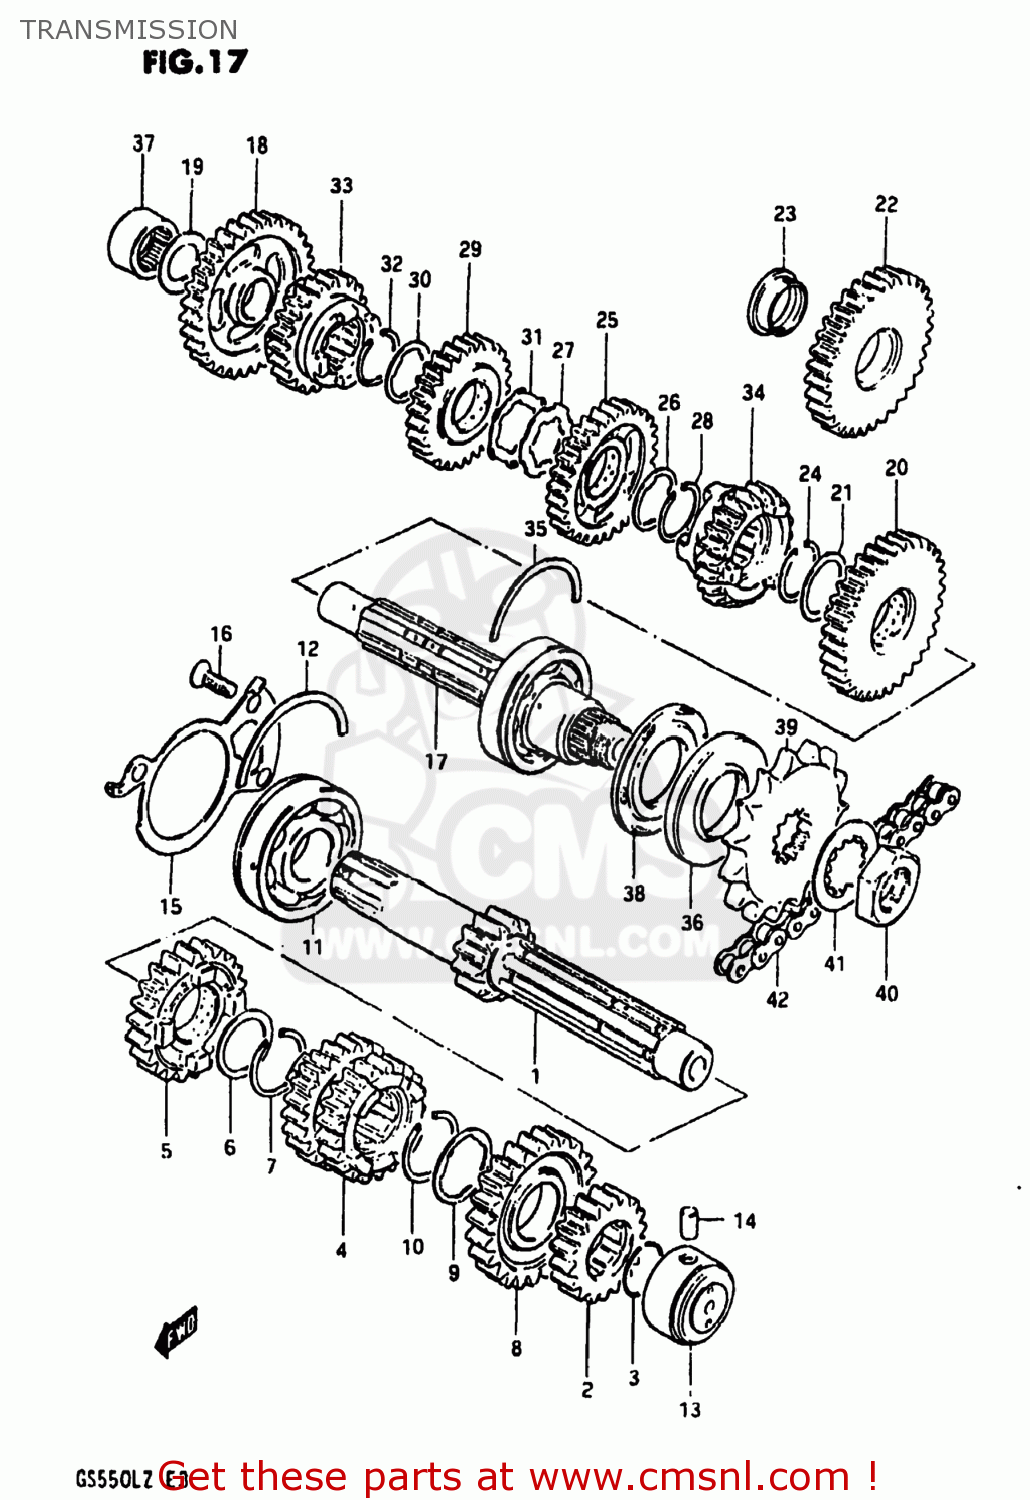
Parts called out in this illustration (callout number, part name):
1	SHAFT,COUNTER
2	GEAR,SECOND DRIVE
3	RING,SNAP
4	GEAR,THIRD DRIVE
5	GEAR,FIFTH DRIVE
6	WASHER
7	CIRCLIP
8	GEAR,SIXTH DRIVE
9	WASHER,LOCK
10	CIRCLIP
11	BEARING(25X62X17)
12	C-RING
13	BEARING
14	PIN
15	PLATE,COUNTERSHAFT BEARING
16	SCREW
17	SHAFT,DRIVE
18	GEAR,FIRST DRIVEN
19	WASHER
20	GEAR,SECOND DRIVEN
21	WASHER
22	GEAR,SECOND DRIVEN
23	BUSHING
24	CIRCLIP
25	GEAR,THIRD DRIVEN
26	WASHER,LOCK
27	WASHER,LOCK
28	CIRCLIP
29	GEAR,FOURTH DRIVEN
30	WASHER,LOCK
31	WASHER
32	CIRCLIP
33	GEAR,FIFTH DRIVEN
34	GEAR,SIXTH DRIVEN
35	C-RING
36	SEAL,OIL(32X62X7)
37	ROLLER BEARING (20X34X1
38	SEAL,OIL(32X62X5.5)
39	SPROCKET,ENGINE
40	NUT
41	WASHER
42	CHAIN ASSEMBLY,DRIVE
